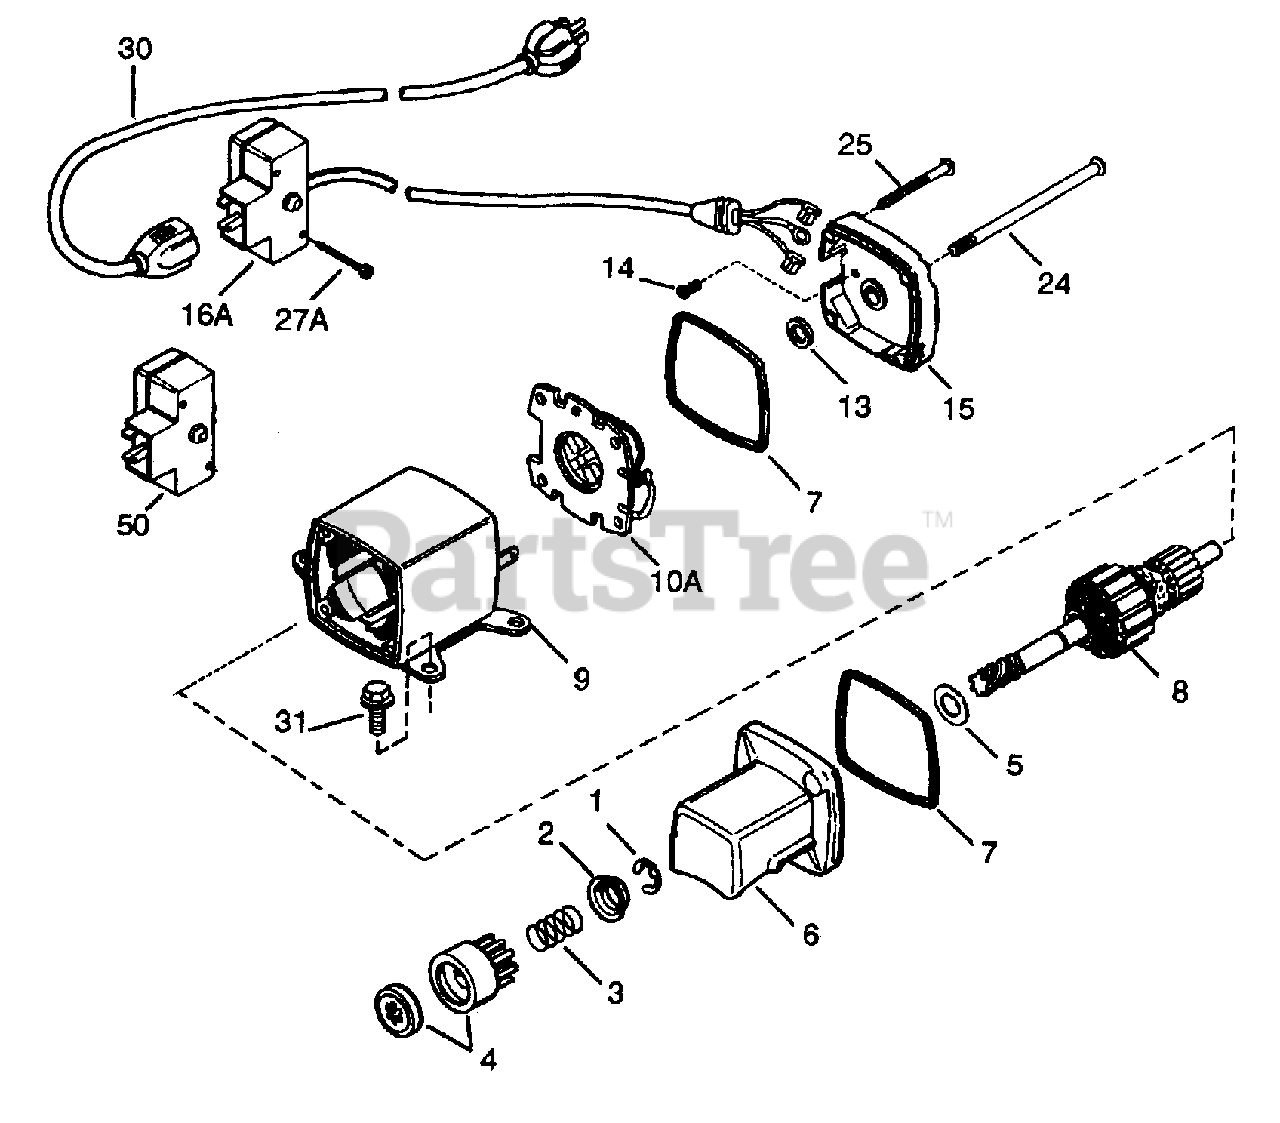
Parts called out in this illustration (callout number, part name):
1	Retainer Ring
2	Spring Retainer
3	Anti-drift Spring
4	Nut & Gear
5	Thrust Washer
6	Drive End Cap Assy
9	Housing Assy
10A	Brush & Spring Card Assy
13	Thrust Washer
14	Ground Screw
15	Commutator End Cap Assy
16A	Switch Box Assy
24	Case Bolt
25	Grounding Screw
27A	Screw, 6-32 x 2-1/2"
30	Extension Cord
31	Screw, Torx T-30, 1/4-20 x 23/32"
50	Switch Repair Kit
